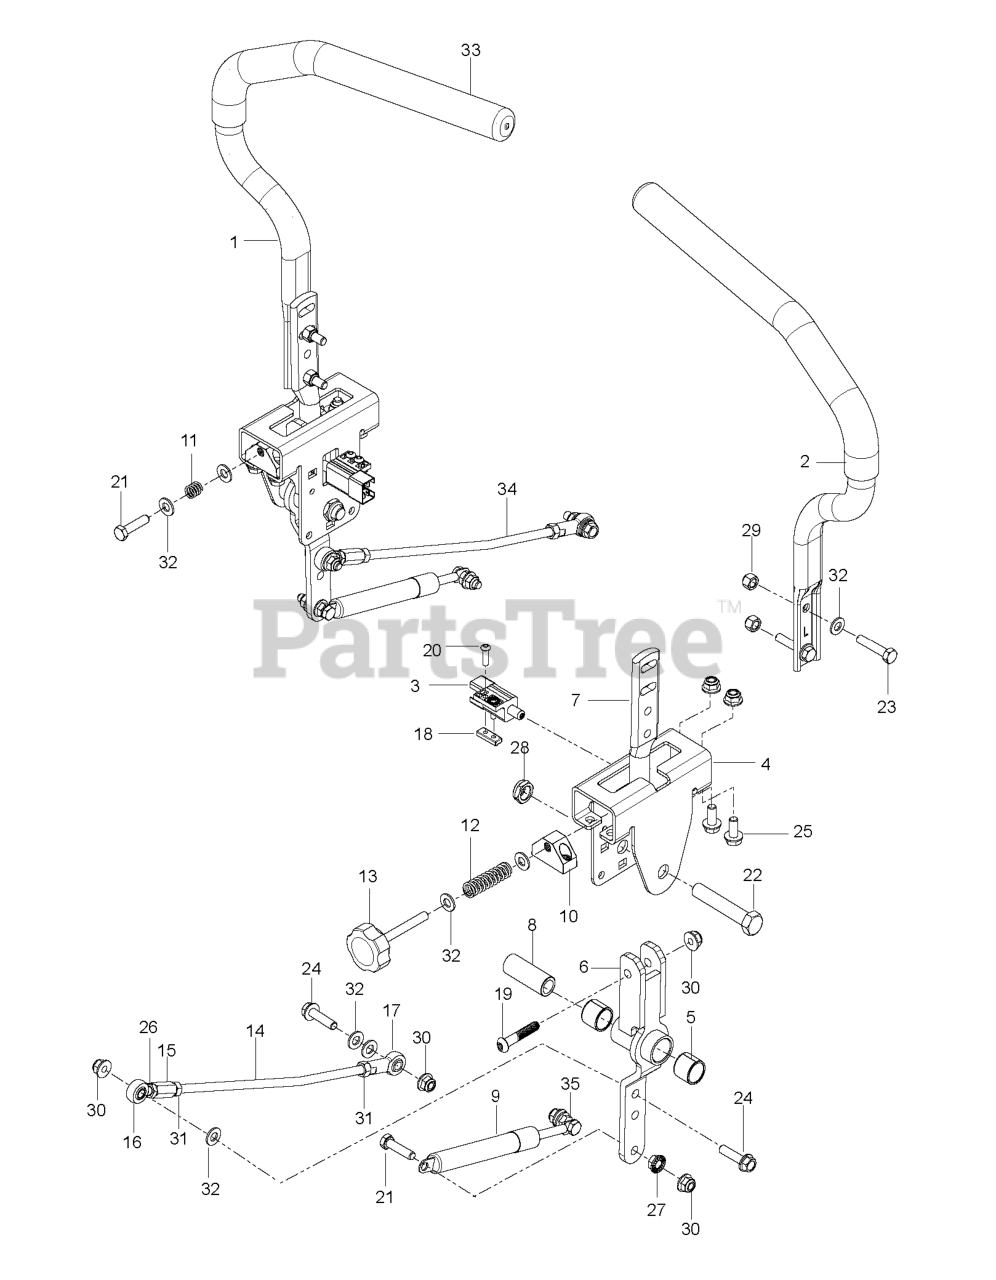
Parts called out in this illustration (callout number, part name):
1	TUBE.LEVER.CONTROL.ZTR.RT.428
2	TUBE.LEVER.CONTROL.ZTR.LT.428
3	SWITCH INTERLOCKT
4	BRACKET.CONTROLS.ZTR.X431
5	BEARING
5	BEARING.PT.750
6	CONTROL.WELDMENT.RZ
7	LEVER.HANDLE MOUNT
8	SPACER.PIVOT.CONTROL
10	BLOCK TRACKING CONTROL ZTR
12	SPRING COMPRESSION 2.0
14	ROD, CONTROL
15	ROD END COUPLER
16	ROD.END.MALE.LH.THREAD
17	JOINT.HEIM.FEML.5/16.RH.THREAD
18	PLATE NUT ZTR
19	NUT 5/16C WHIZ
19	SCREW 5/16-18 X 1 3/4 BTN-HD
20	SCR #10-24 X .75 SKT HD BLK
21	HCS 1/2-13 X 2-3/4 GD 5 ZD
21	BOLT.5/16-18X1-1/4 FULL.THREAD
22	HCS 1/2-13 X 2-3/4 GD 5 ZD
22	CAPSCREW 5/16 X 1/1/2 HEX HEAD
23	HHFS 5/16-18 X 1.25 TPBLT GD 5
23	CAPSCREW 5/16 X 1/1/2 HEX HEAD
24	HHFS 5/16-18 X 1.25 TPBLT GD 5
24	HHFS 5/16-18 X 3/4
25	SCREW 5/16-18 X 1 3/4 BTN-HD
25	HHFS 5/16-18 X 3/4
26	NUT 5/16F LEFTHAND
27	NUT 5/16C WHIZ
28	NUT 1/2-13 HEX JM NYL
28	NUT 5/16 NYLOC
29	NUT 5/16 NYLOC
29	5/16-18 NYLOC FLANGE NUT
30	5/16-18 NYLOC FLANGE NUT
30	WASHER
32	WASHER
33	GRIP - DRIVE LEVER 12"
34	BOLT.5/16-18X1-1/4 FULL.THREAD
35	NUT 1/2-13 HEX JM NYL
